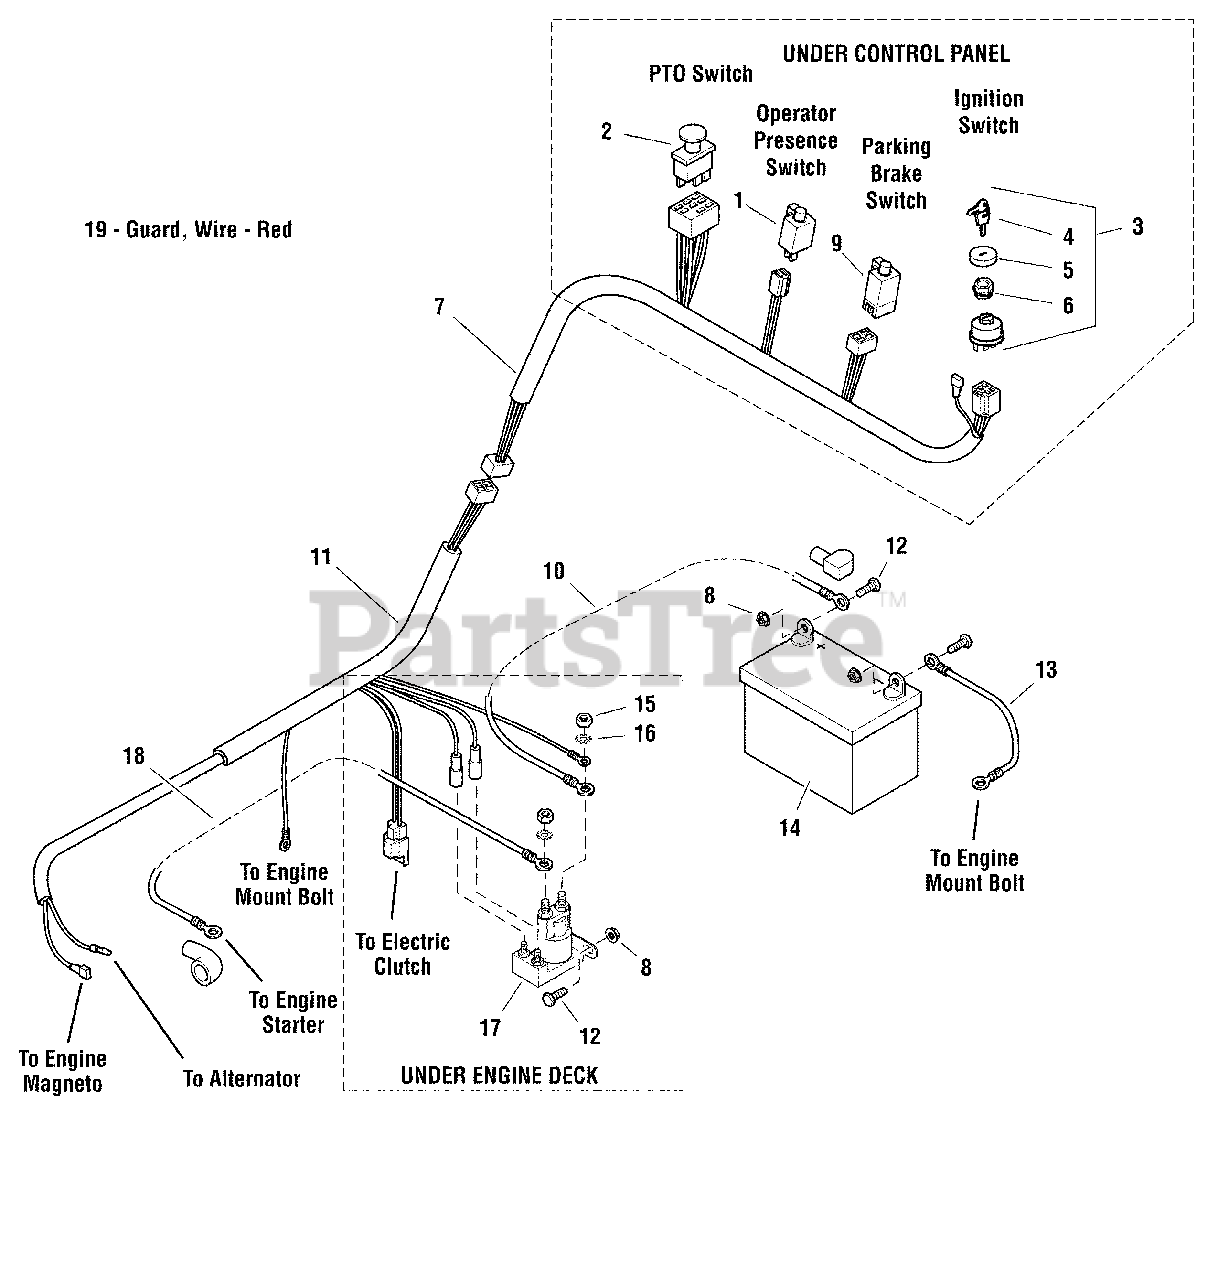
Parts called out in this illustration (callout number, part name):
1	SWITCH, PLUNGER NC
2	SWITCH, BLADE ENGAGEMENT
3	SWITCH, IGNITION, 6 POST
4	KEY, IGNITION MOLDED SET
5	COVER, PLASTIC, SNAP ON
6	PLASTIC NUT
7	WIRE HARNESS, HANDLE BAR
8	NUT, 1/4-20 HEX SERRATED FLANGE
9	SWITCH, PLUNGER, NO/NO, BOLT-IN
10	BATTERY CABLE, POSITIVE, 22"
11	WIRE HARNESS, ENGINE DECK, KAWASAKI
12	BOLT, 1/4-20 X 3/4
13	BATTERY CABLE, NEGATIVE, 22"
14	BATTERY, WET ( BCIU1, 340 CCA)
15	NUT, HEX JAM 5/16-24
16	WASHER, LIGHT LOCK, 5/16
17	SOLENOID-4 POLE 12 VOLT DC (TROMBETTA)
18	BATTERY CABLE, POSITIVE, 35"
19	GUARD, WIRE - RED
